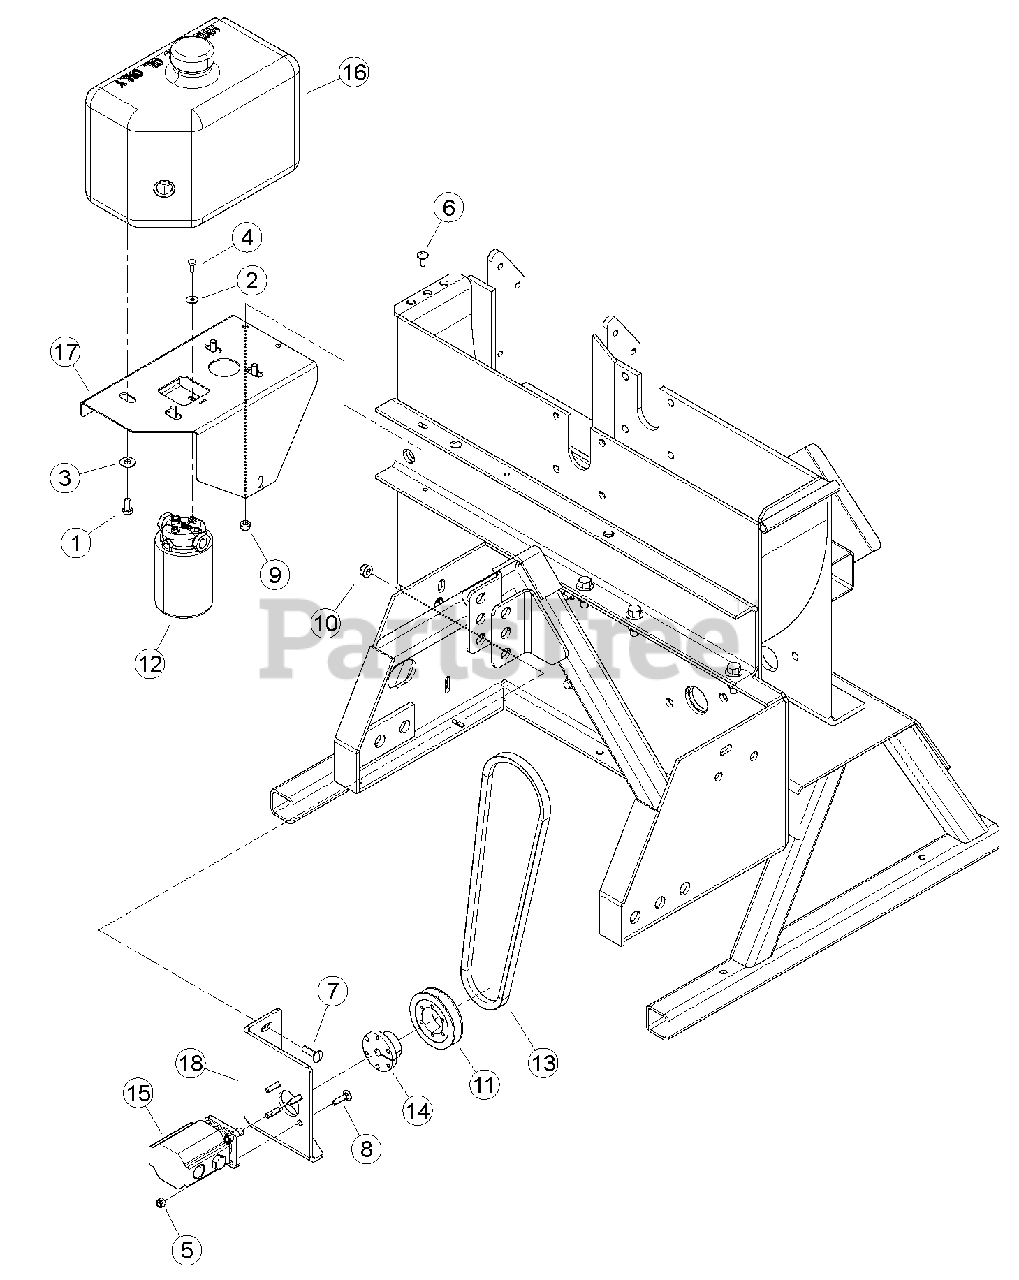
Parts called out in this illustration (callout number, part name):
1	BOLT, 3/8 X 3/4 GR5 HEX CAPSCREW ZP
2	WASHER, 1/4 FLAT
3	WASHER, 3/8 FLAT
4	BOLT, 1/4 X 5/8" HHCS GR5 ZP
5	NUT, 5/16-18 NE NYLOCK
6	BOLT, 5/16 X 3/4 GR5 CRG NC ZP
7	BOLT, 3/8-16 X 1-1/4 GR5 CRG
8	BOLT, 5/16 X 1-1/4 GR5 CRG
9	NUT, 5/16-18 NYLOCK FLANGE
10	NUT, 3/8-16 NYLOCK FLANGE
11	SHEAVE, 1B3.6 SH
12	ASSEMBLY, HYDRAULIC FILTER
13	BELT, BX44
14	BUSHING, SH 1/2"
15	PUMP, 2 STAGE CW HI/LO 0.605 DISP.
16	TANK, HYDRAULIC
17	WELDMENT, HYDRAULIC TANK BRACKET
18	WELDMENT, BRACKET MOUNT HYDRAULIC PUMP
